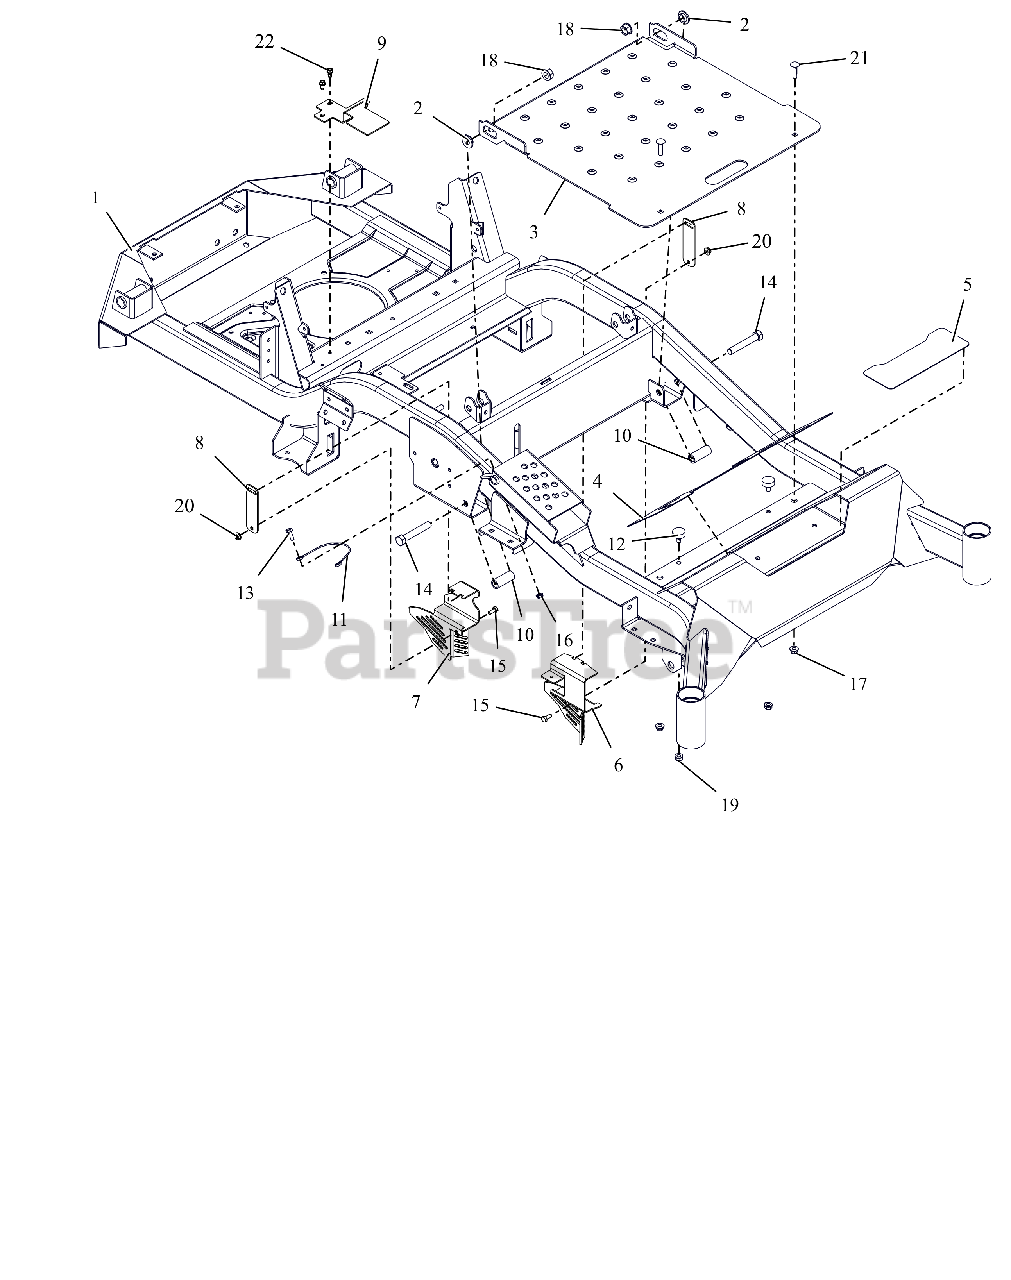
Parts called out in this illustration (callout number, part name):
1	APEX,44-52 FRAME W/SAFETY DECA
2	BSHG-FLG .515X.750X.395X1.120
3	PANEL, ACCESS
4	GRIP, FRONT
5	GRIP, STEP
6	GUARD, TRANSAXLE FAN-LH
7	GUARD, TRANSAXLE FAN - RH
8	BRKT,TRANSAXLE FAN GUARD
9	GUARD, TRANSAXLE FAN RH (BLACK)
10	SPACER, .515X.75X1.83
11	CABLE, 12.0 LANYARD, NYLON
12	BUMPER, RUBBER
13	BLT, HEX .25-20X.75 G5 ZCC
14	BLT, HEX .50-13X3.00 G5 ZCC
15	BLT, HEX .25-20X.625 G5 ZCC
16	NUT,NYL-FLG .25-20 GF ZCC
17	NUT,LK-NYL-FLG .31-18 G5ZC120
18	NUT,FLG-TOP LK .625-11 FBP
19	NUT,SPNLK-FLG .31-18 G5 ZCC
20	NUT-LK-TOP-FLG .250-20 GF ZCC
21	BLT, RHSSN.31-18X1.25 G5 ZCC
22	SCR-TAP .25-20X.50 HWH ZCC
